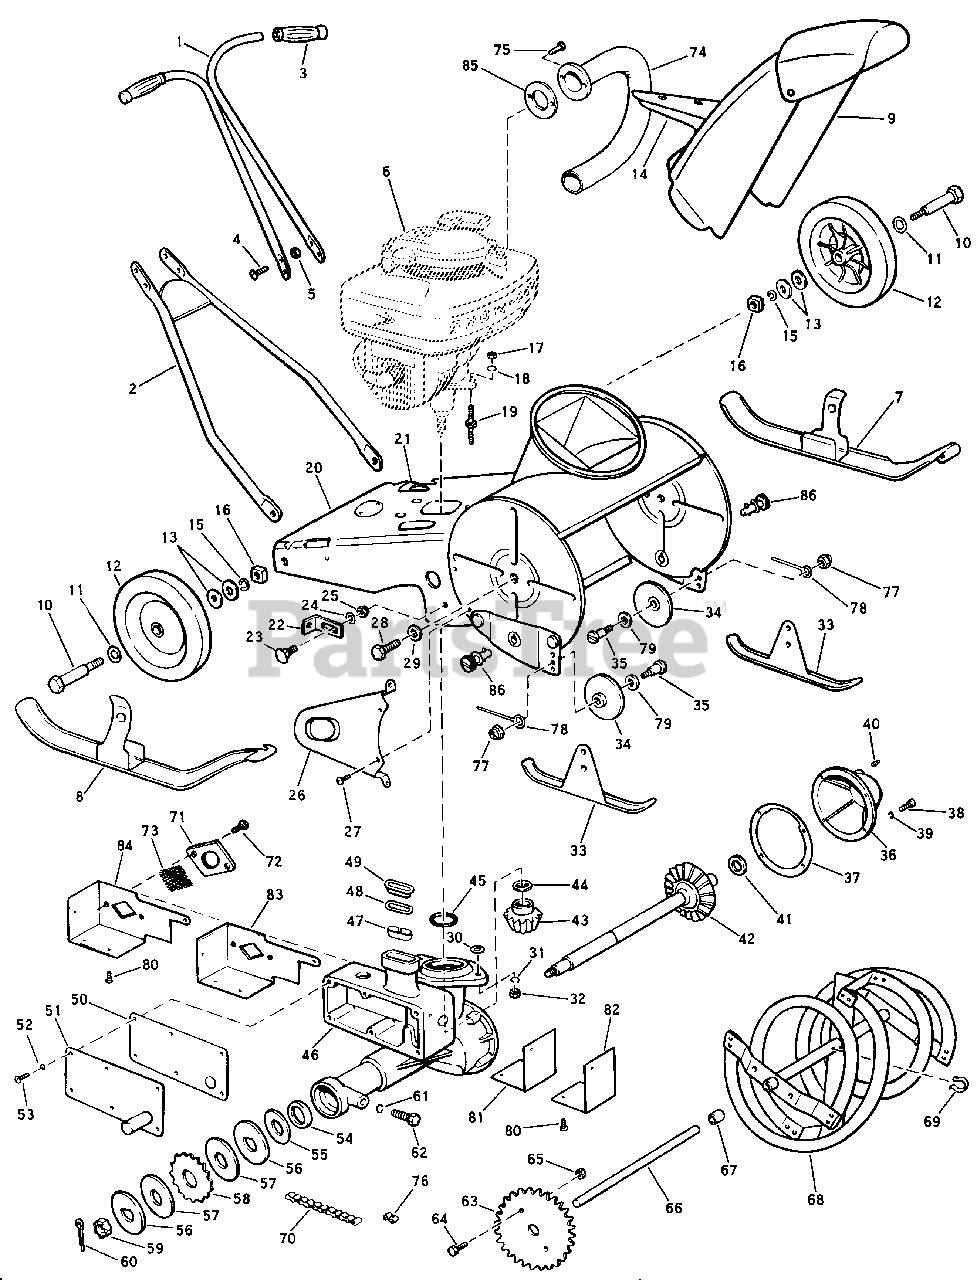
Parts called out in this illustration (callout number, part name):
1	Handle Assembly-Upper
2	Handle Assembly-Lower
3	Grip-Handle
4	Screw-Handle
5	Nut-Handle Screw
6	Engine Assembly
7	Ski-Left
8	Ski-Right
9	Chute Assembly
10	Shoulder Bolt-Wheel Mounting
11	Washer-Outer-Wheel
12	Wheel Assembly-Rear
13	Washer-Inner-Wheel
14	Positioning Pin
15	Lockwasher-Wheel Mounting Nut
16	Nut-Wheel Mounting Screw
17	Nut-Engine Mounting
18	Lockwasher-Engine Mounting-Nuts
19	Stud-Gearcase and Engine Mounting
20	Base and Housing Assembly
21	Latch-Handle Lock
22	Stabilizer Bracket
23	Carriage Bolt-Stabilizer Bracket
24	Washer-Stabilizer Bracket Bolt Nut
25	Locknut-Stabilizer Bracket Bolt
26	Guard-Chain
27	Screw-Chain Guard
28	Screw-Impeller Shaft to Housing
29	Lockwasher-Impeller Shaft Screw
30	Washer-Gearcase to Base Stud
31	Lockwasher-Gearcase Mounting Nut
32	Nut-Gearcase Mounting
33	Ski-Front
34	Wheel Assembly-Front
35	Stud-Front Wheel
36	Cover-Gearcase
37	Gasket-Gearcase Cover
38	Screw-Gearcase Cover
39	Lockwasher-Gearcase Cover Screw
40	Plug-Oil Fill-Gearcase
41	Thrust Washer-Driveshaft Gear
42	Driveshaft and Gear Assembly
43	Pinion gear
44	Thrust Washer-Pinion Gear
45	"O" Ring-Gearcase to Crankcase
46	Gearcase and Muffler
47	Liner-Muffler to Cylinder
48	Gasket-Exhaust
49	Sleeve-Exhaust
50	Gasket-Muffler Cover
51	Muffler Cover and Outlet Pipe
52	Lockwasher-Muffler Screw
53	Screw-Muffler Cover
54	Oil Seal-Gearcase to Driveshaft
55	Washer-Belleville Clutch
56	Washer-Steel-Drive Shaft Sprocket
57	Washer-Fiber-Driveshaft Sprocket
58	Sprocket-Driveshaft
59	Nut-Driveshaft
60	Cotter Pin-Driveshaft
61	Lockwasher-Stabilizer Bracket Screw
62	Screw-Stabilizer Bracket
63	Sprocket-Impeller Shaft
64	Screw-Sprocket to Impeller
65	Locknut-Sprocket Screw
66	Impeller Shaft
67	Bushing-Impeller Hub
68	Impeller and Hub Assembly (Includes item 69)
69	Spring Clip-Oil Hole Cover, Impeller Hub
70	Drive Chain
71	Cover-Air Intake-Muffler
72	Screw-Air Intake Cover Muffler
73	Screen-Air Intake-Muffler
74	Heat Exchanger Tube and Insulating Sleeve
75	Screw-Heat Exchanger to Carburetor
76	Connecting Link
77	Locknut-Front Wheel
78	Spring-Stud Retainer
80	Screw-Shield to Muffler
81	Muffler-Insulation-Small
82	Muffler-Shield-Small
83	Muffler-Insulation-Large
84	Muffler-Shield-Large
86	Stud, Bow Washer and Pin Assembly
